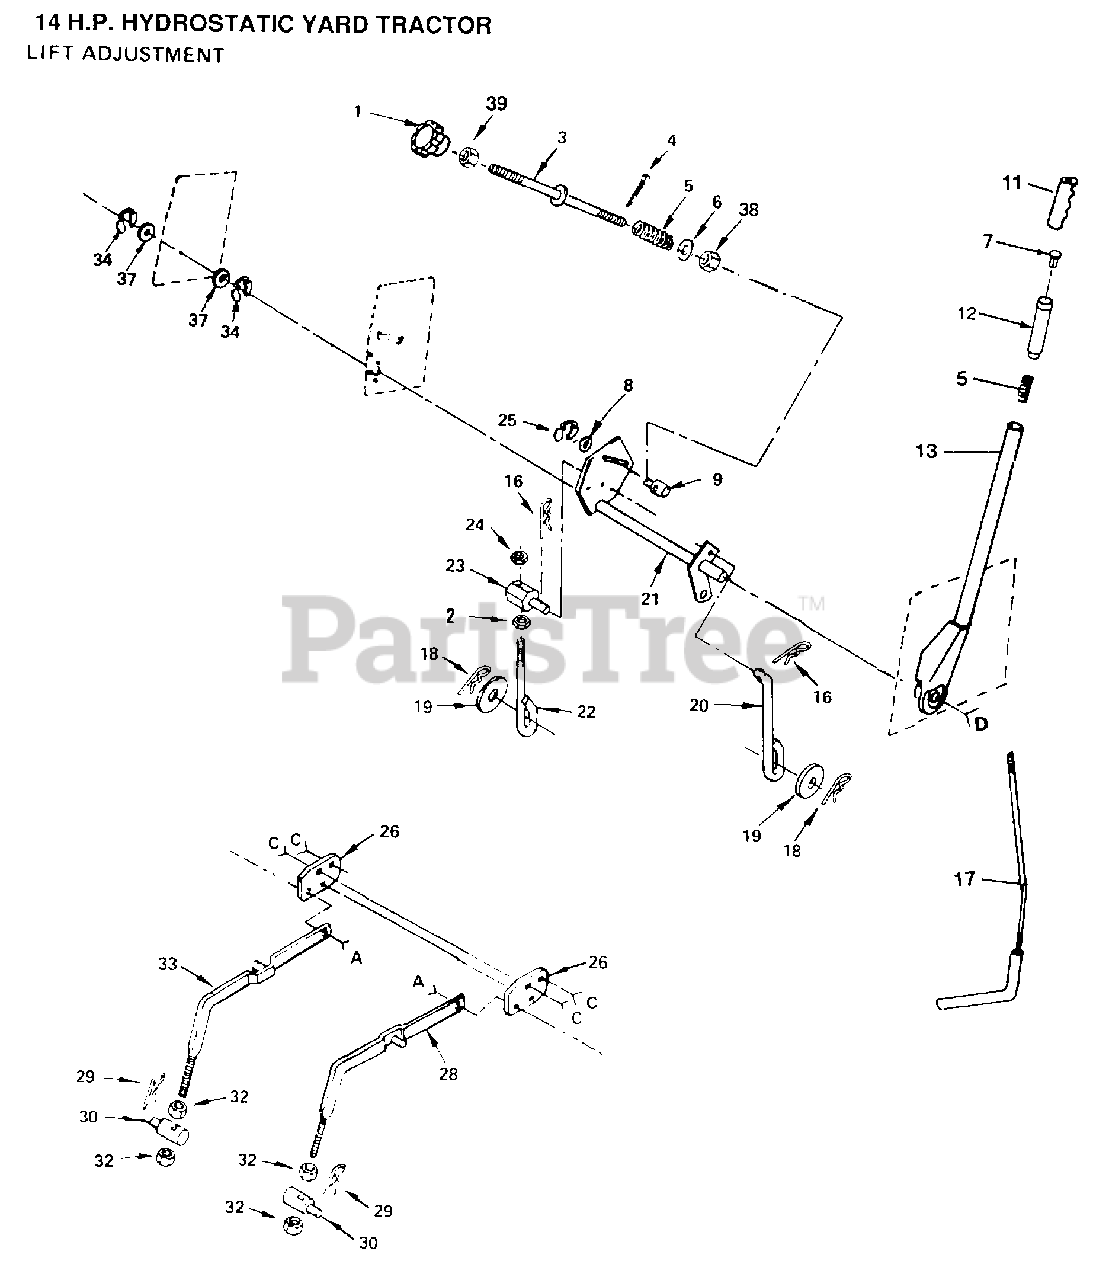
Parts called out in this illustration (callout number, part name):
2	NUT
3	ROD LIFT LT
5	SPRING T
6	WASHER
8	WASHER
9	TRUNION LT
11	GRIP
17	LEVER ROD LT
18	SPRING.RETAINER
20	LIFT LINK LT
22	PIVOT PIN T
25	KLIP RING
26	"BRACKET, SUSPE T"
28	RH SUSP ARM ASM
29	SPRING H
32	NUT
33	LH SUSP ARM ASM
34	E-RING
37	WASHER
38	NUT T
39	NUT
